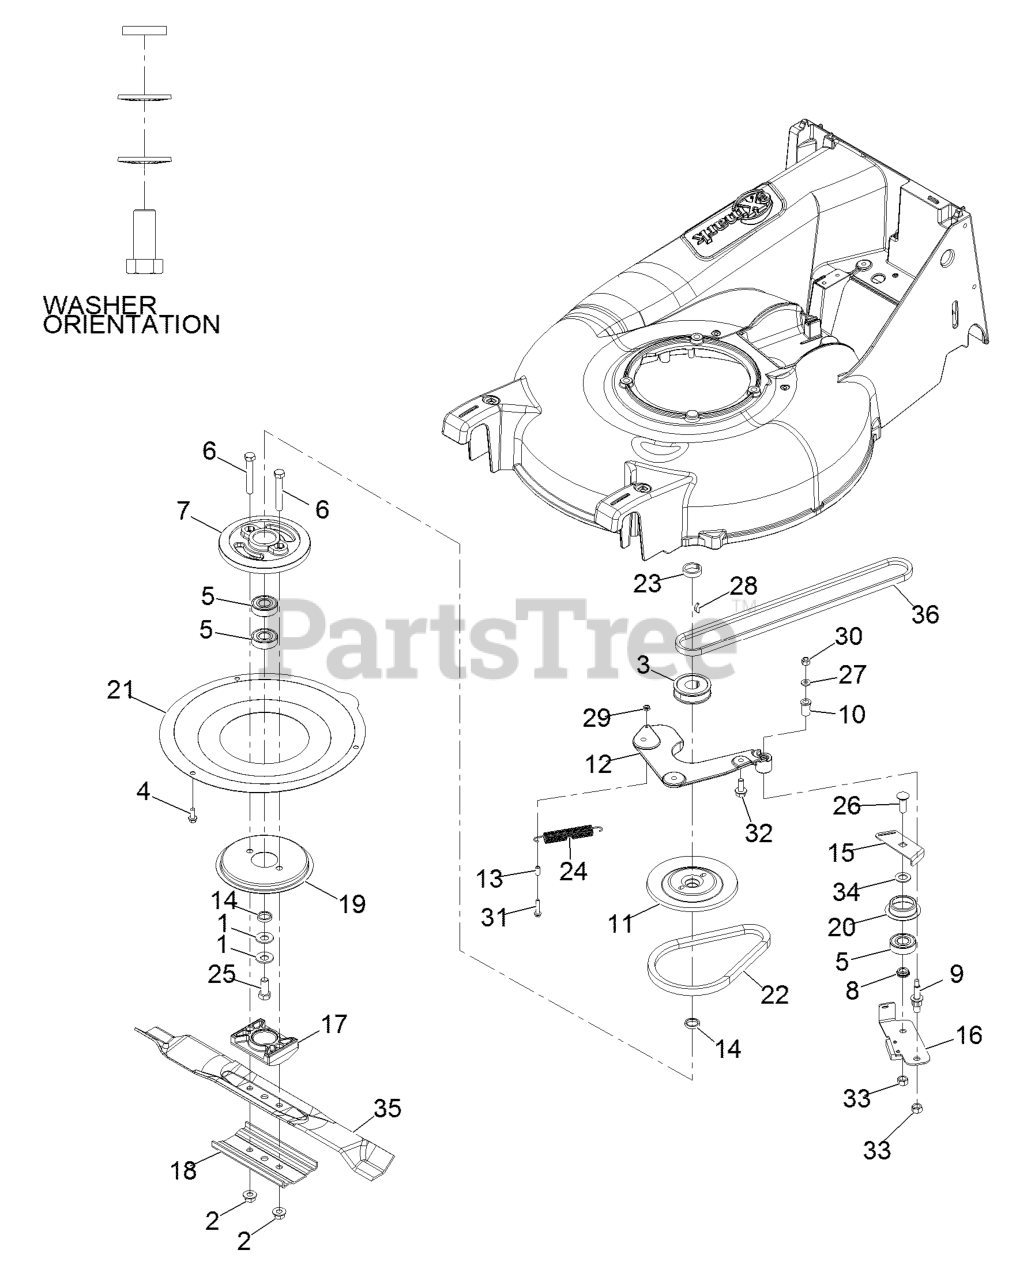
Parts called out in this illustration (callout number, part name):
1	WASHER-SPRING
2	NUT-FLANGE, LOCK
3	PULLEY-DRIVER
4	SCREW-HWH
6	SCREW-HH
8	SPACER-BEARING
9	BOLT-SHOULDER
10	BUSHING
11	PULLEY-DRIVER, UPPER
12	PLATE-MOUNTING, BBC
13	SPACER-BBC
14	SPACER-PLATE, BBC
15	PLATE-GUIDE
16	PLATE-BRAKE
17	SUPPORT-BLADE
18	SUPPORT-BLADE
19	DISC
20	RETAINER-BELT
21	COVER-BBC
22	BELT
23	SPACER-PULLEY
24	SPRING-EXTENSION
25	SCREW-HH
26	SCREW-CARR
27	WASHER-FLAT
28	KEY-WOODRUFF
29	NUT-LOCK, NI
30	NUT-LOCK, NI
31	SCREW-TAP
32	SCREW-HHF
33	NUT-HEX
34	SPACER
36	BELT,3L P21 DRIVE
